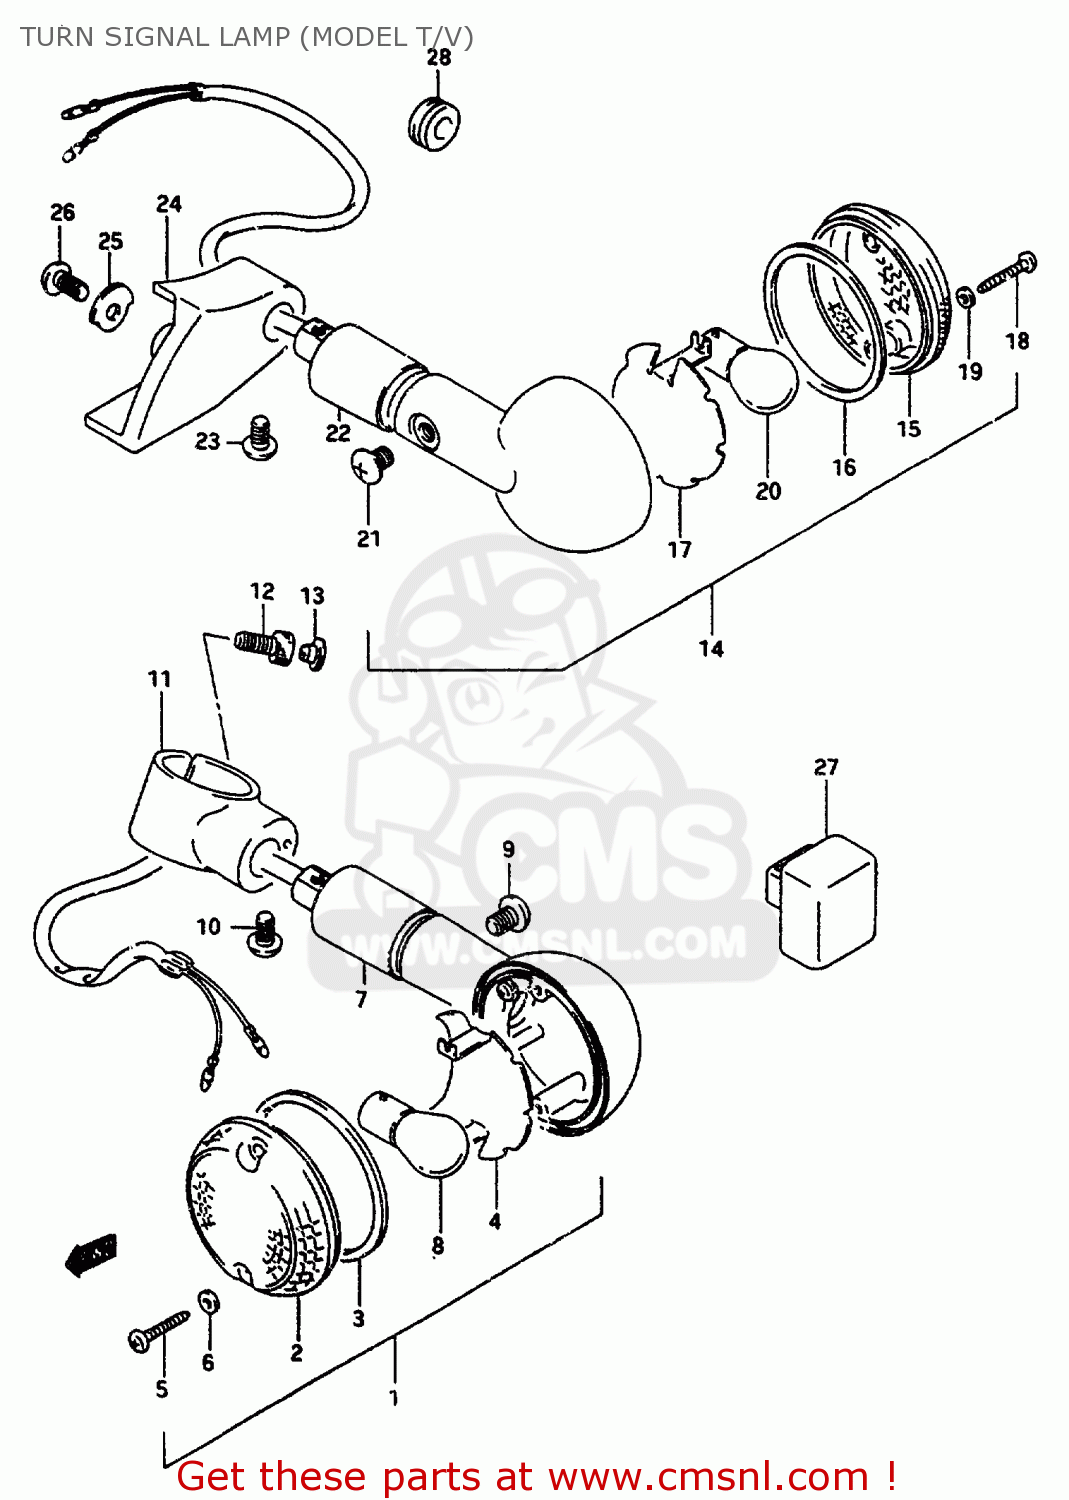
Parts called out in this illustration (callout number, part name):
1	LAMP ASSY,FR TURN SIGNAL
2	LENS
3	GASKET (NAS)
4	REFLECTOR
5	SCREW
6	GASKET (NAS)
7	STAY,TURNSIGNAL LAMP
8	BULB(12V21W)
9	SCREW
10	SCREW
11	BRACKET,FR TURNSIGNAL LAMP,R
12	BOLT
13	CAP(OD:10)
14	LAMP ASSY,RR TURNSIGNAL,R
15	LENS
16	GASKET (NAS)
17	REFLECTOR
18	SCREW
19	GASKET (NAS)
20	BULB(12V21W)
21	SCREW
22	STAY,TURNSIGNAL LAMP
23	SCREW
24	BRACKET,TURN R
25	WASHER,RR TURNSIGNAL BRACKET
26	SCREW 6X12
27	RELAY ASSY,TURNSIGNAL LAMP
28	GROMMET
29	RELAY ASSY,TURNSIGNAL LAMP
